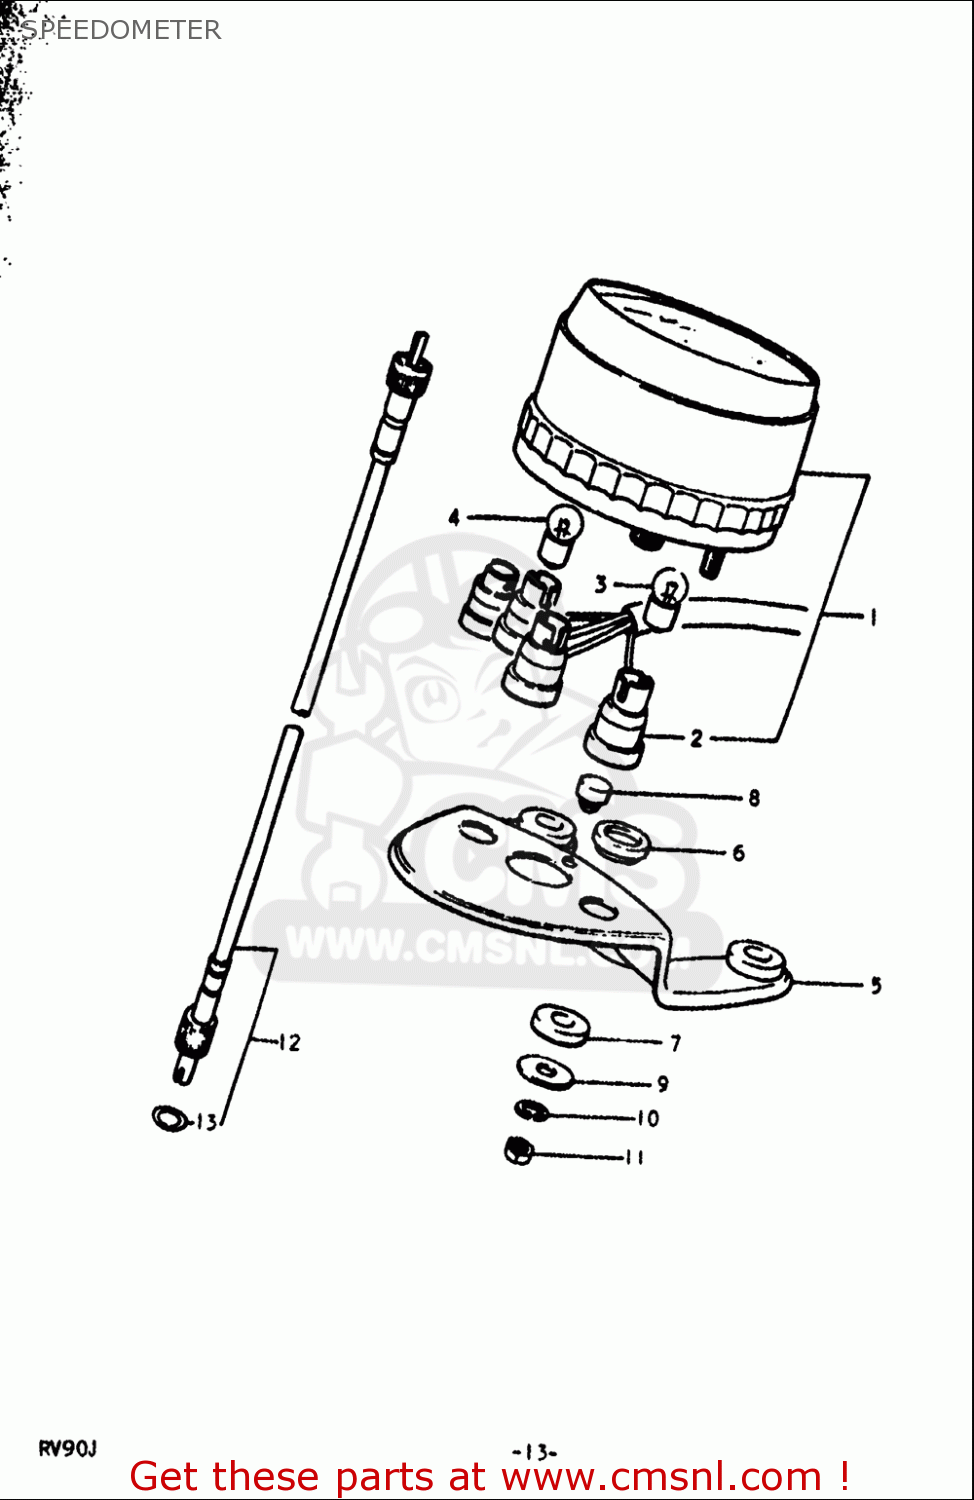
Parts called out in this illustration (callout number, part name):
3	BULB(6V/3W)
4	BULB(6V1.7W,STANLEY,A61A)
6	CUSHION,METER
7	CUSHION
10	WASHER,LOCK
11	NUT
12	CABLE ASSY,SPEEDOMETER
13	SEAL,OIL METER CABLE
